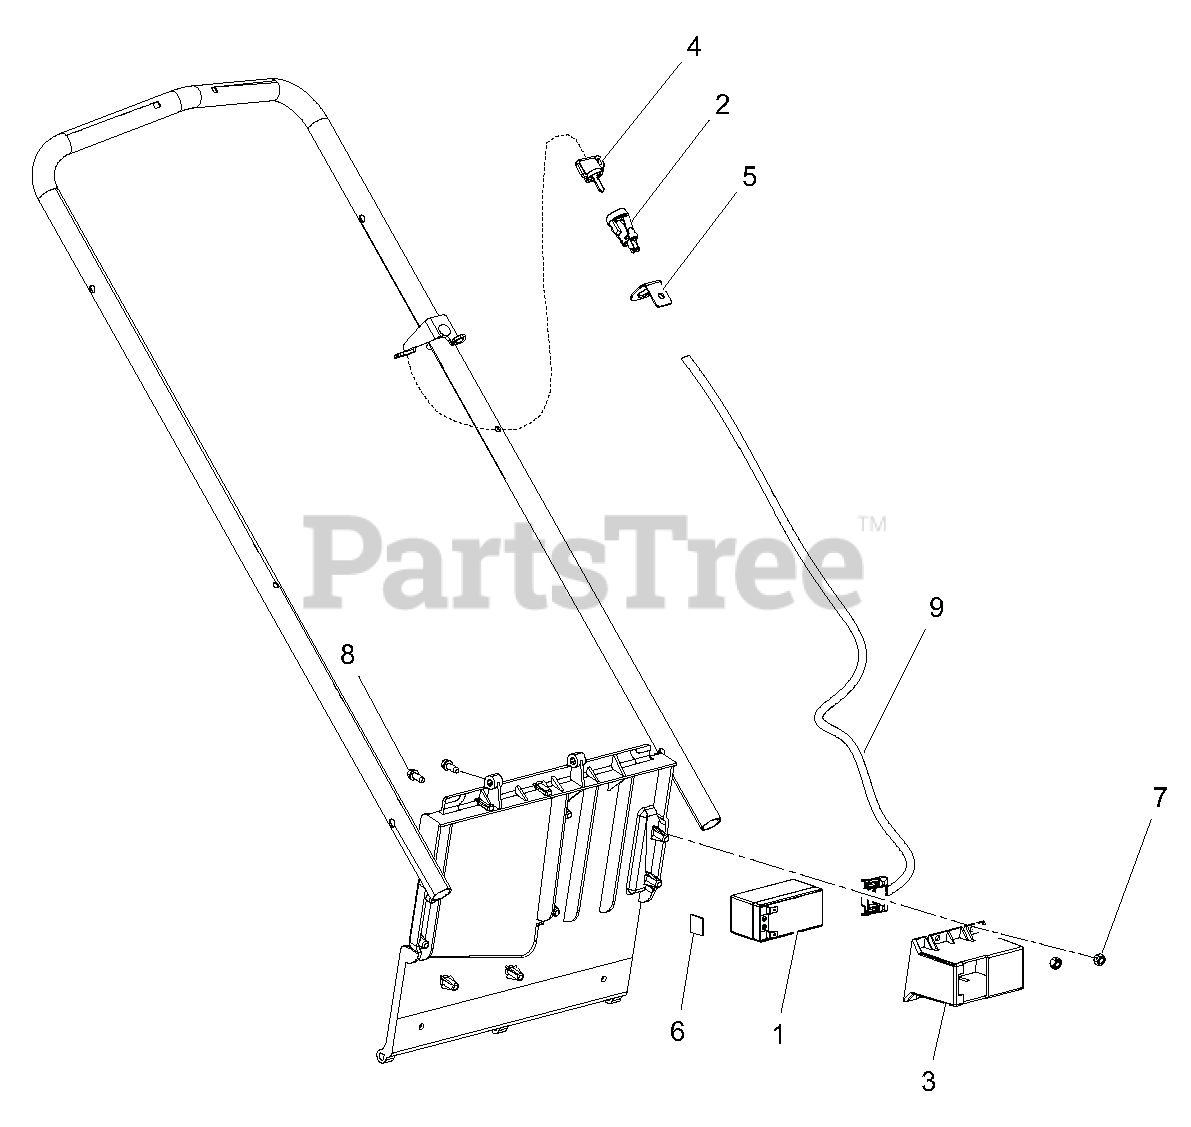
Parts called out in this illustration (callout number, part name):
1	BATTERY,LM(SEE BULLETIN B2117)
2	SWITCH, KEY
3	COVER, BATTERY
4	KEYS, IGNITION
5	BRKT, KEY SWITCH
7	@NUT-LK-CTR .25-20 YWZC
8	@SCR-TAP .25-20X.62 HWH TR YWZ
9	HARNESS, ELEC START - SUBARU
10	CHARGER, BATTERY - CE
